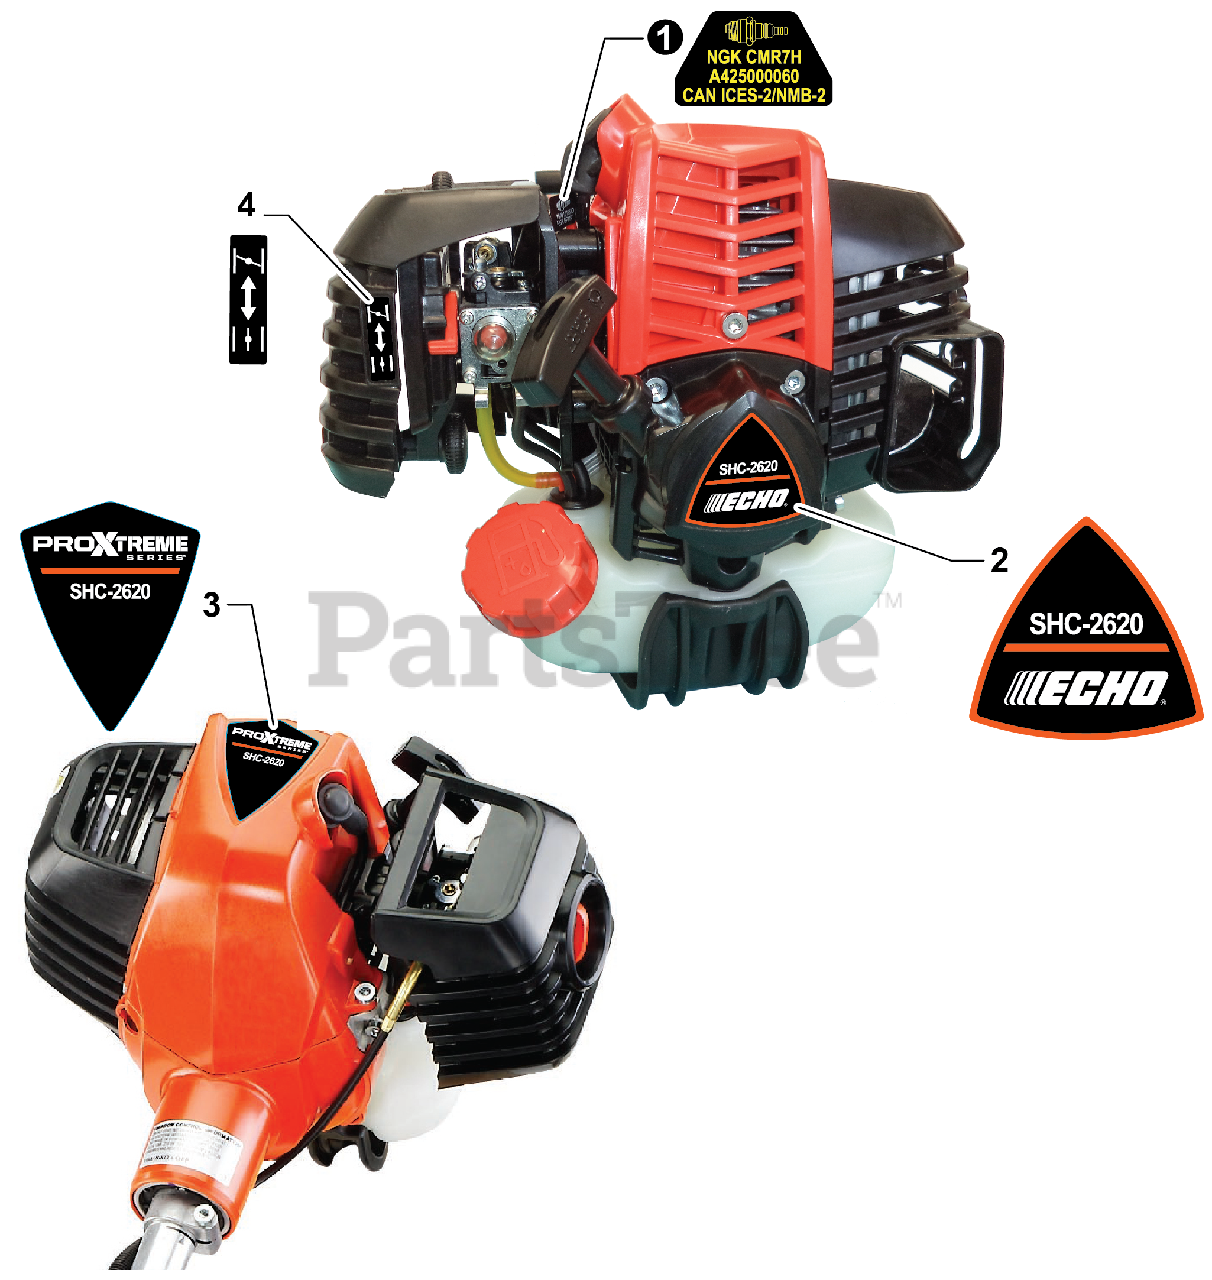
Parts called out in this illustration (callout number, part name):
1	LABEL, SPARK PLUG - CMR7H
2	LABEL, RECOIL STARTER - SHC-2620
3	LABEL - MODEL SHC-2620
4	LABEL, CHOKE
